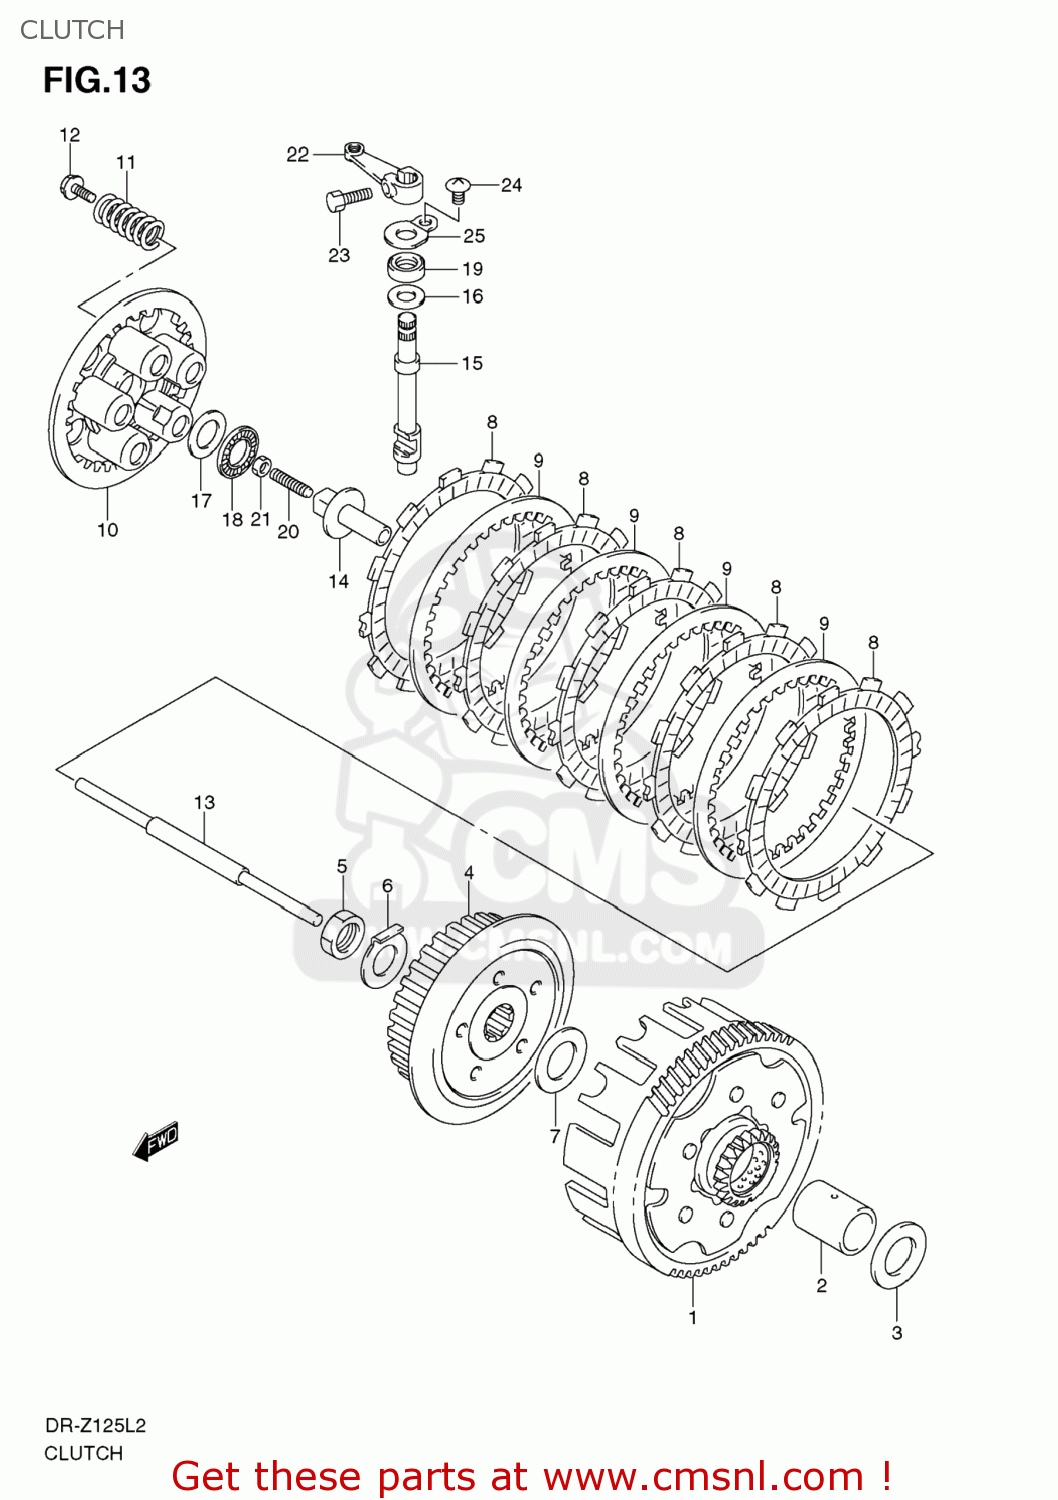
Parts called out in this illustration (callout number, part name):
1	GEAR ASSY,PRI DRIVEN(NT:59)
2	SPACER,PRIMARY DRIVEN
3	WASHER
4	HUB,CLUTCH SLEEVE
5	NUT
6	WASHER
7	WASHER
8	PLATE,CLUTCH DRIVE (NAS)
9	PLATE,CLUTCH DRIVEN (NAS)
10	DISC,CLUTCH PRESSURE
11	SPRING
12	BOLT(5X16)
13	ROD,CLUTCH PUSH
14	PIECE,CLUTCH PUSH
15	CAMSHAFT,CLUTCH RELEASE
16	SHIM(10X20X1)
17	WASHER(15.5X28X1)
18	BEARING(15X28X2)
19	SEAL,OIL(10X20X6)
20	SCREW(6X25)
21	NUT
22	ARM,CLUTCH RELEASE
23	BOLT
24	SCREW
25	RETAINER,CL RLSE OIL SEAL
